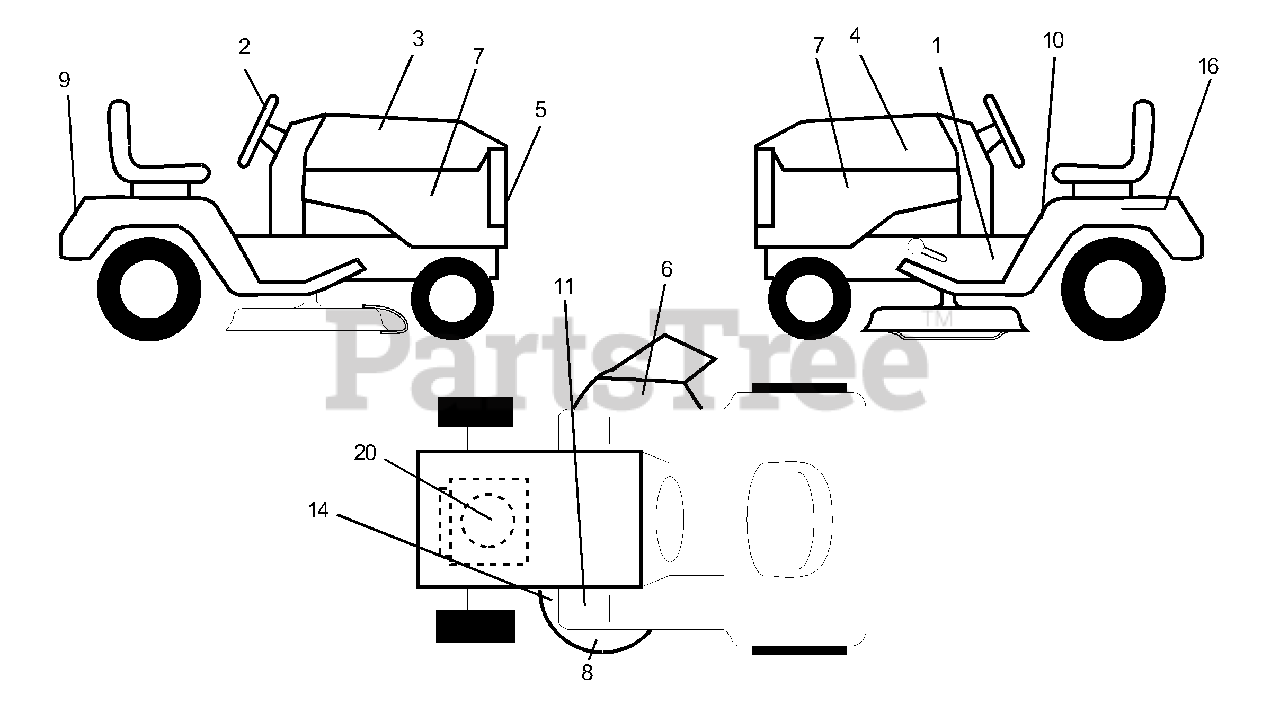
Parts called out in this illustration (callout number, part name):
1	Decal Instruction Operat English
2	Decal Ins Strg Wh
3	Decal Hood Rh
4	Decal Hood Lh
5	Decal Grille Logo
6	Decal, Warning
7	Decal Panel Side
8	Decal Deck Grasseater
9	Decal Fender Logo
10	Decal Danger English
11	Decal Clutch/brake English
14	Decal V-belt Schematic 42"
16	Decal Battery Danger/Poison
20	Decal HP Engine
